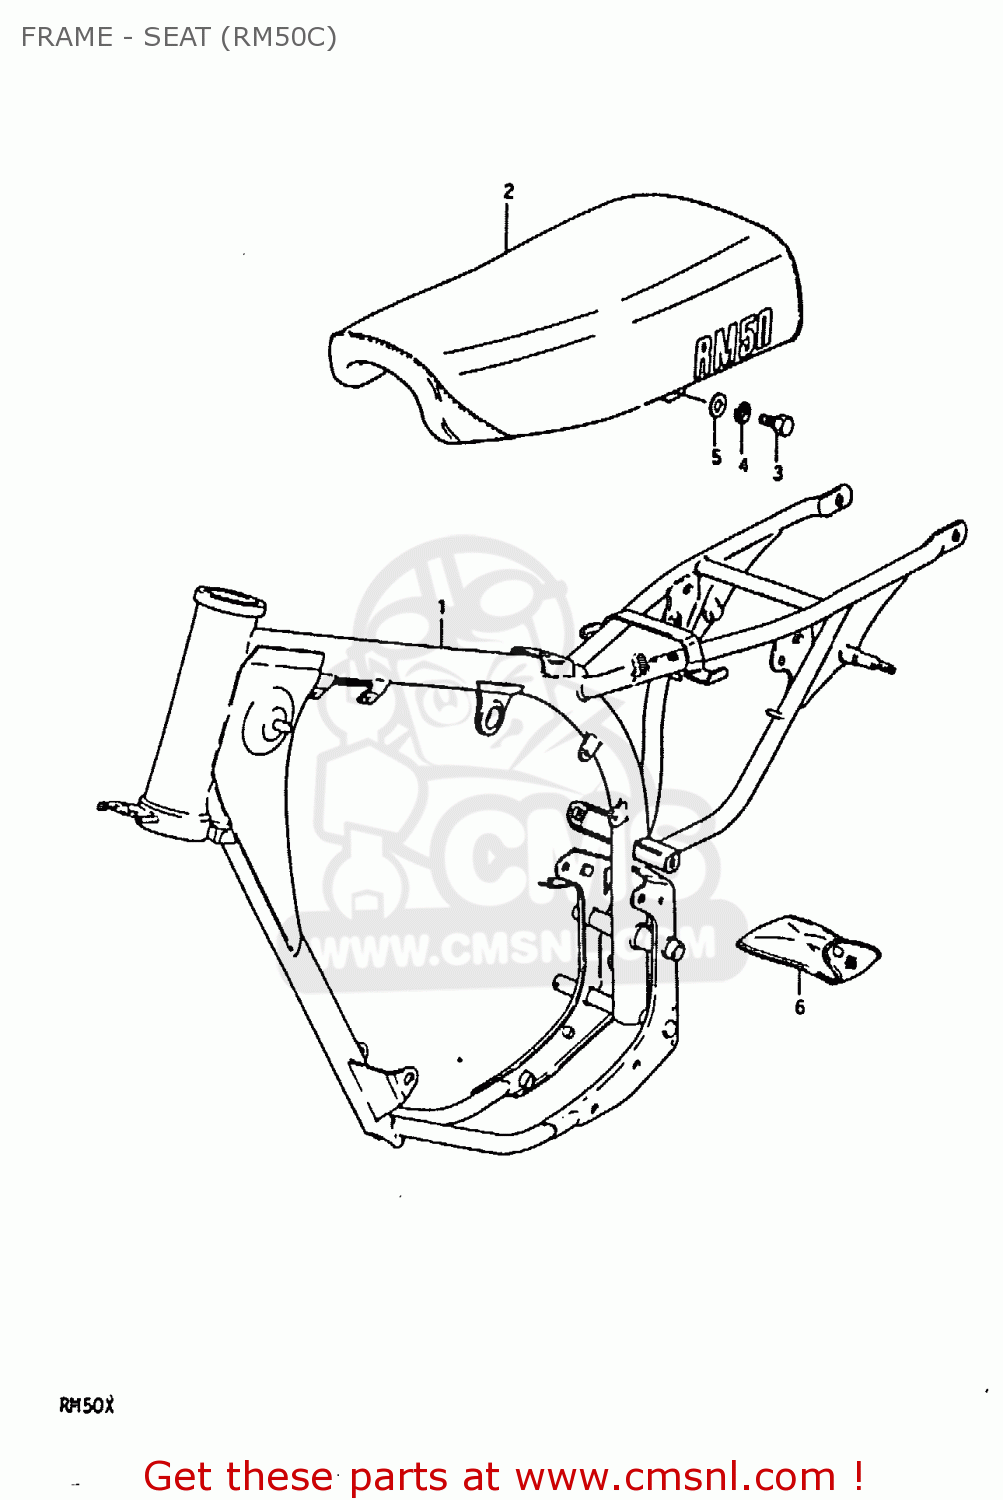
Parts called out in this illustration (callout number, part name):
1	FRAME
2	SEAT ASSEMBLY
3	BOLT
4	LOCK WASHER
5	WASHER
6	TOOL SET
